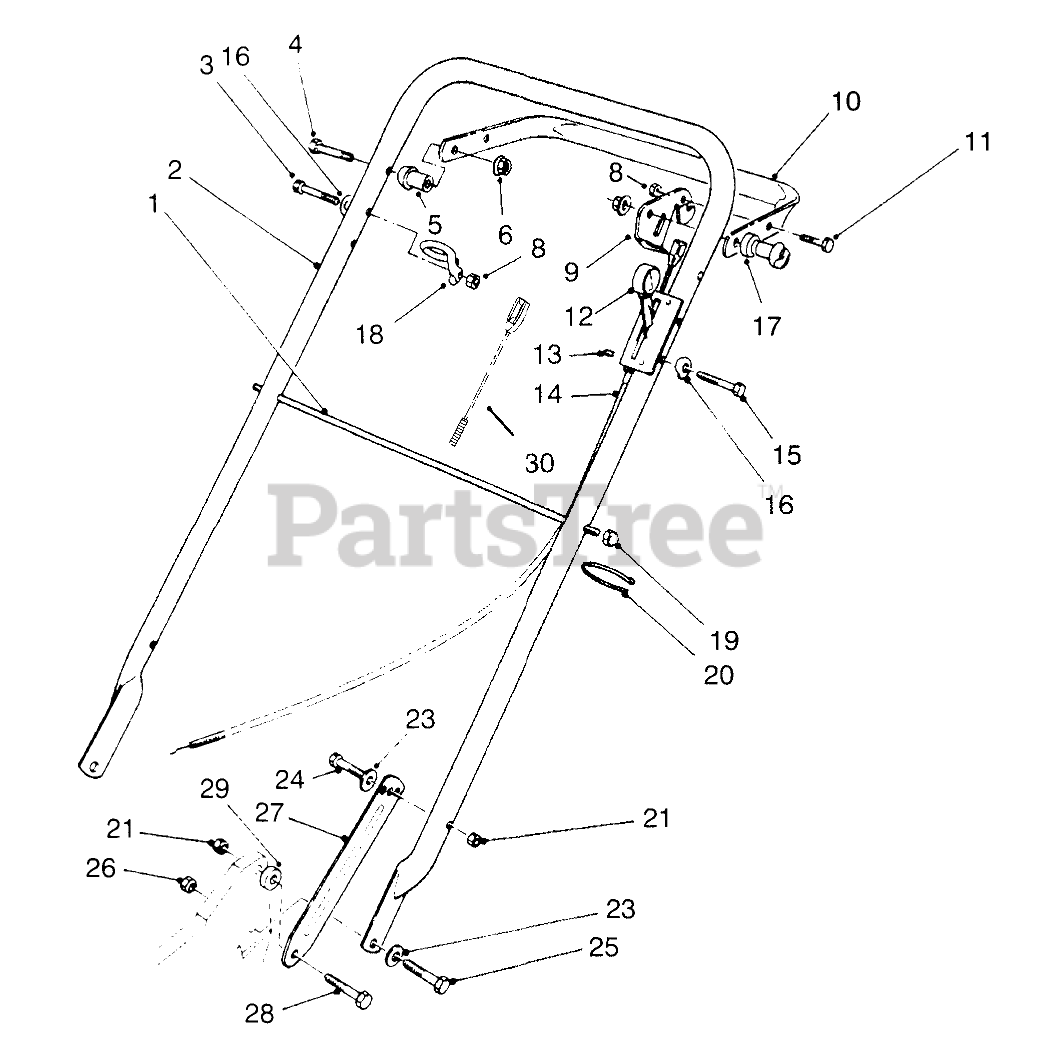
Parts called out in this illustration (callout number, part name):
1	ROD-SUPPORT, BAG
2	Handle
3	SCREW-HH
4	SCREW-HH
5	SPACER-SUPPORT
6	NUT-LOCK, NI
8	NUT-LOCK, NI
9	LEVER-CONTROL
10	Bar-Control
11	SCREW-HH
12	CONTROL-THROTTLE
13	E-RING
14	CABLE - THROTTLE
15	SCREW-HH
16	WASHER
17	SPACER-NYLON
18	GUIDE-ROPE
19	NUT-CAP
20	TIE-CABLE
21	NUT-LOCK, NI
23	WASHER-BELLEVILLE
24	SCREW-HH
25	SCREW-HH
26	NUT-LOCK, NI
27	Latch-Handle
28	SCREW-SHOULDER
29	SPACER
30	CABLE - BRAKE
